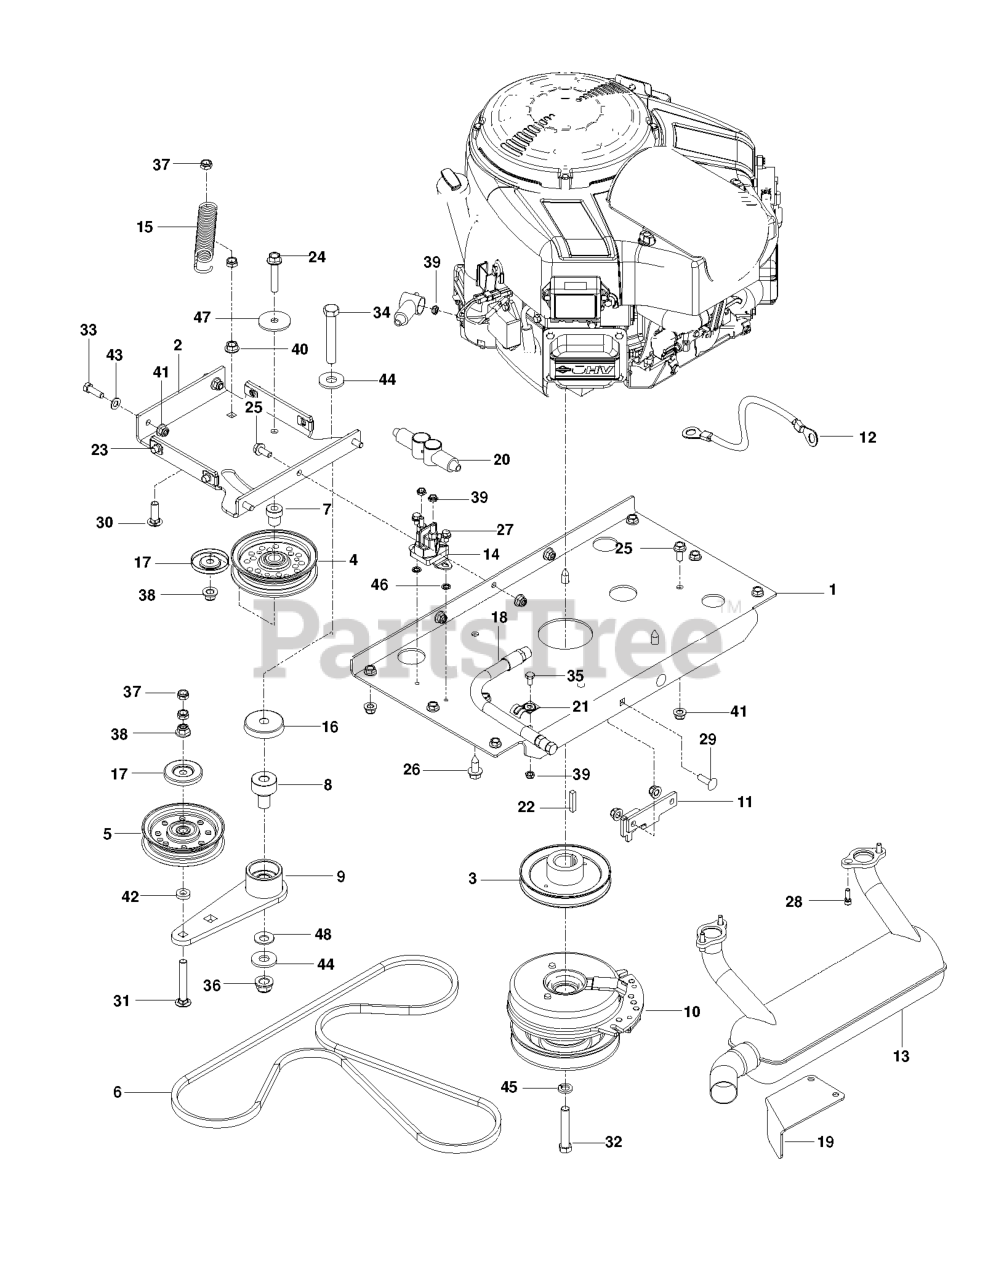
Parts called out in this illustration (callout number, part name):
1	PLATE, ENGINE, BLK
2	PLATE, IDLER, BLK
3	PULLEY, V, 1.125 BORE
4	IDLER PULLEY
5	FLAT IDLER PULLEY
6	BELT, HYDRO, 3400
7	PIVOT, IDLER
8	PIVOT, BEARING
9	ARM, IDLER, STEEL, W/BGS
10	CLUTCH 200 FT LB
11	STOP, CLUTCH, BLACK
12	CABLE POSITIVE
13	MUFFLER, B&S CYCLONIC
15	SPRING, PUMP
16	SHIELD, DUST
17	DUST SHIELD
18	HOSE.ASSEMBLY.OIL.DRAIN
19	SHIELD MUFFLER
22	KEY, 1/4 SQ X 1 1/4
23	U-CLIP 5/16-18 NUT RETAINER
24	HHFS 3/8-16 X 2.0 GD 5
25	HHFS 5/16-18 X 3/4
26	HHFS 3/8-16 X 1.0 THD FORMING
27	HWST 1/4C X 3/8
28	SCREW.SOCKET.HEAD.5/16-18
29	RHSSNB 5/16C X 1.0
30	RHSNB 3/8-16 X 1-1/4
31	RHSNB 3/8-16 X 2.75
32	BOLT 7/16F X 2 1/2
33	HCS 5/16C X 1
34	HCS 1/2C X 3 1/4
35	HCS 1/4-20.
36	NUT, 1/2-13 HEX FLG NYLOC ZD
37	NUT HEX 3/8-16 NYLON, THIN
38	NUT 3/8-16 HEX FLG NYLOC ZD
39	JAM NUT 1/4C (2 2 PW01)
40	NUT 3/8C WHIZ
41	5/16-18 NYLOC FLANGE NUT
42	WASHER 3/8 X 3/4 X .187 TK
43	FLAT WASHER 5/16 SAE
44	WASH USS FLAT 1/2
45	WASHER 7/16 LOCK
46	WASHER 1/4 INT TOOTH
47	WASHER, 3/8 SPEC
48	CONTACT BELLSPR 1/2
